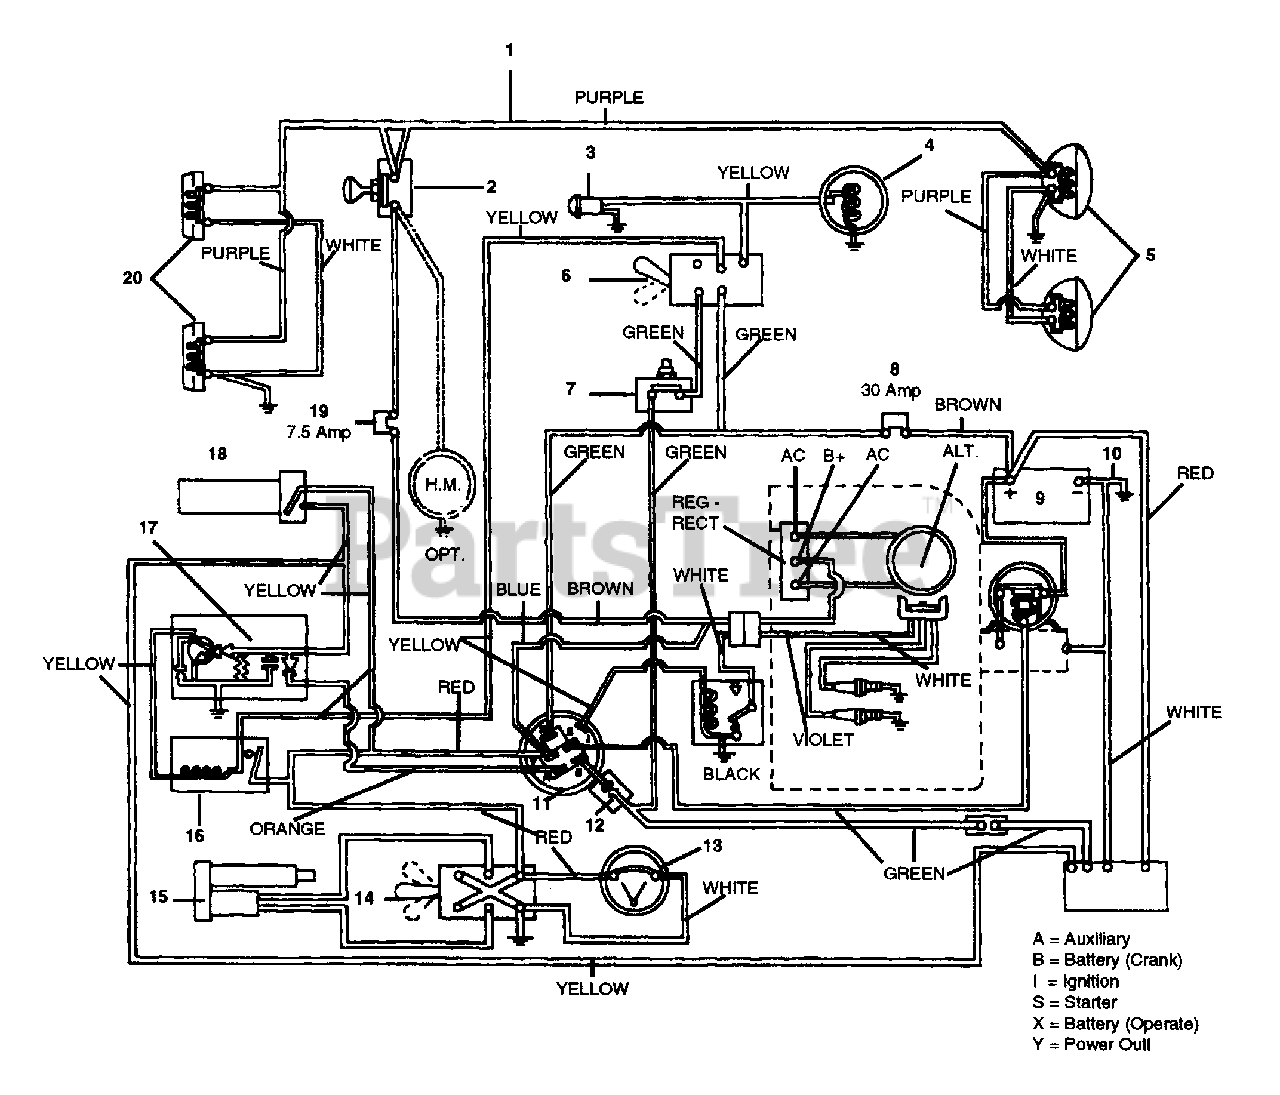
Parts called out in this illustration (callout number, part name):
1	WIRING HARNESS
2	LIGHT SWITCH ASSEMBLY
2	LIGHT SWITCH
3	PTO INDICATOR LIGHT
3	LAMP SOCKET
3	SPEED NUT
4	ELECTRIC CLUTCH
5	HEADLIGHT BULB, 1156
6	SWITCH ASSEMBLY
7	SAFETY SWITCH
8	30 Amp Fuse
9	BATTERY
10	GROUND CABLE .25X6.50X.31
11	SWITCH ASSEMBLY
12	DIODE ASSEMBLY
13	VOLTMETER
14	SWITCH ASSEMBLY
15	ACTUATOR
16	RELAY
17	TIME DELAY MODULE
18	SWITCH SEAT
19	7.5 Amp Fuse
20	#168 Wedgge Base TailLight Bulb
